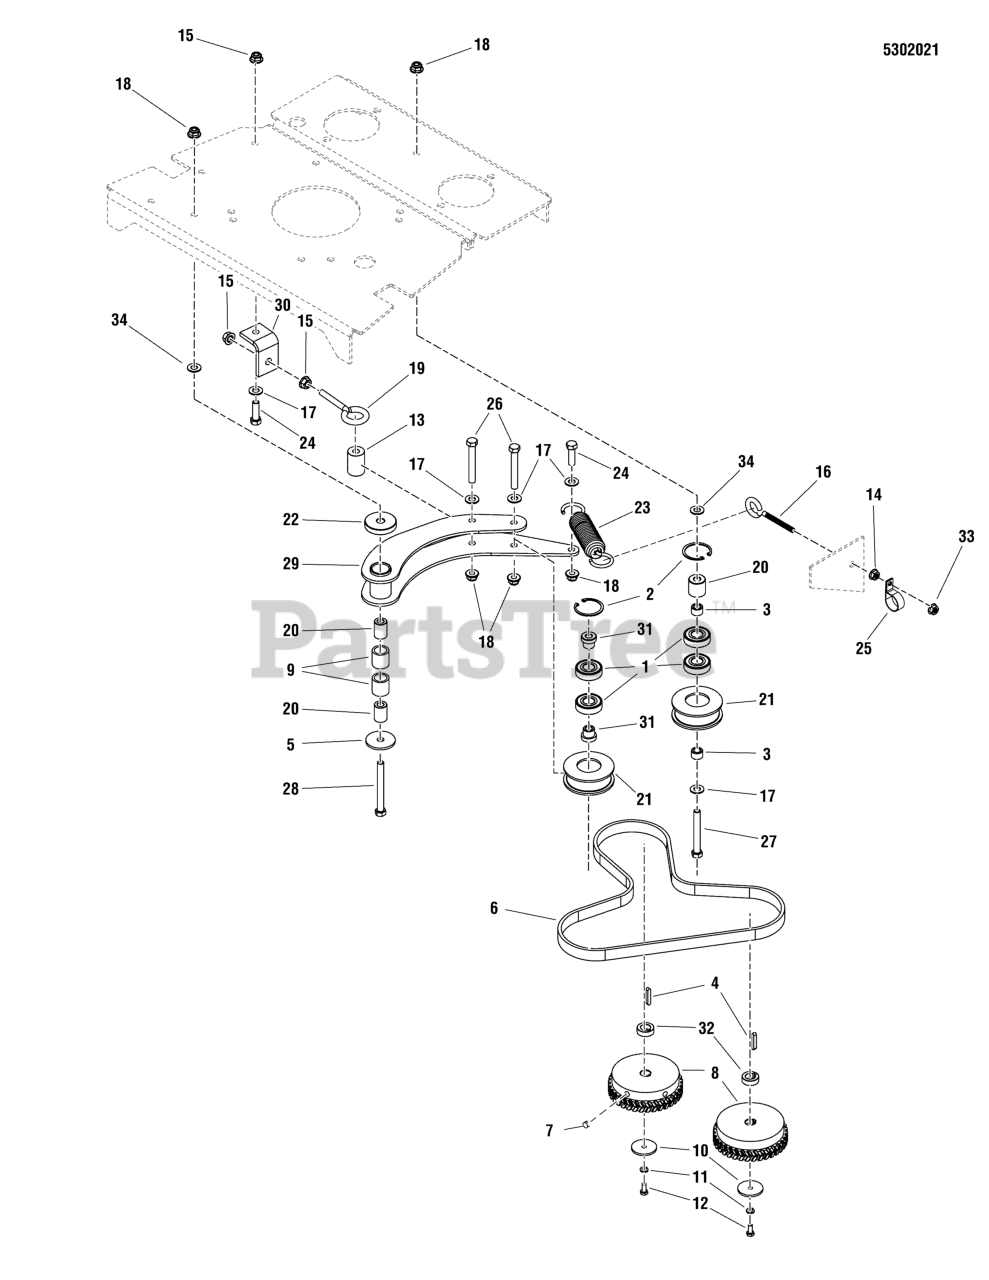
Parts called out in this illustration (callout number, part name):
1	BEARING, BALL 11/16X1-9/16X15/32
2	SNAP RING, INTERNAL
3	INSERT, BEARING, 17MM X 12MM L
4	KEY, 5MM SQ. W/ RADIUS
5	WASHER, .41 X 1.75 X .14
6	BELT, SPROCKET DRIVE
7	SET SCREW, 5/16-18 X 3/8 PCH.
8	SPROCKET, 44T X .591 BORE, EAGLE PD
9	BUSHING, BRASS, 3/4 X 1 X 1
10	WASHER, .265 X 1.50 X .109, YZ
11	WASHER, 1/4 LOCK
12	CAPSCREW-HEX HEAD M6-1.0X 14MM
13	SPACER, .39 X 1.00 X 1.47, YZ
14	NUT, 5/16-18 HEX SERRATED FLANGE (SMALL)
15	NUT, 3/8-16 HEX SERRATED FLANGE
16	EYE BOLT, 5/16-18 X 2-3/4 THRD.
17	WASHER, 3/8 SAE
18	NUT, 3/8-16 HEX NYLOCK FLANGE
19	EYE BOLT, 3/8-16 X 5, 2.88THRD, 1EYE, CZ
20	SPACER, .39 X .75 X 1.06
21	PULLEY, BACKSIDE IDLER, STEEL
22	SPACER, .45 X 1.88 X .38
23	SPRING, EXTENSION, SWIVEL, SHORT HOOK
24	BOLT, 3/8-16 X 1-1/4" GD5 CZ
25	CLAMP, HOSE, 1.000 DIA.
26	BOLT, 3/8-16 X 2-3/4" GD5 CZ
27	BOLT, 3/8-16 X 3" GD5 CZ
28	BOLT, 3/8-16 X 3-1/2" GD5 CZ
29	WELD, IDLER ARM - RED
30	MOUNT, ANCHOR - RED
31	INSERT, BEARING
32	BUSHING, 15MM X 25MM X 8.6MM - KEYED
33	NUT, 5/16-18 HEX NYLOCK FLANGE
34	WASHER, .390 X 1.50 X .109, YZ
